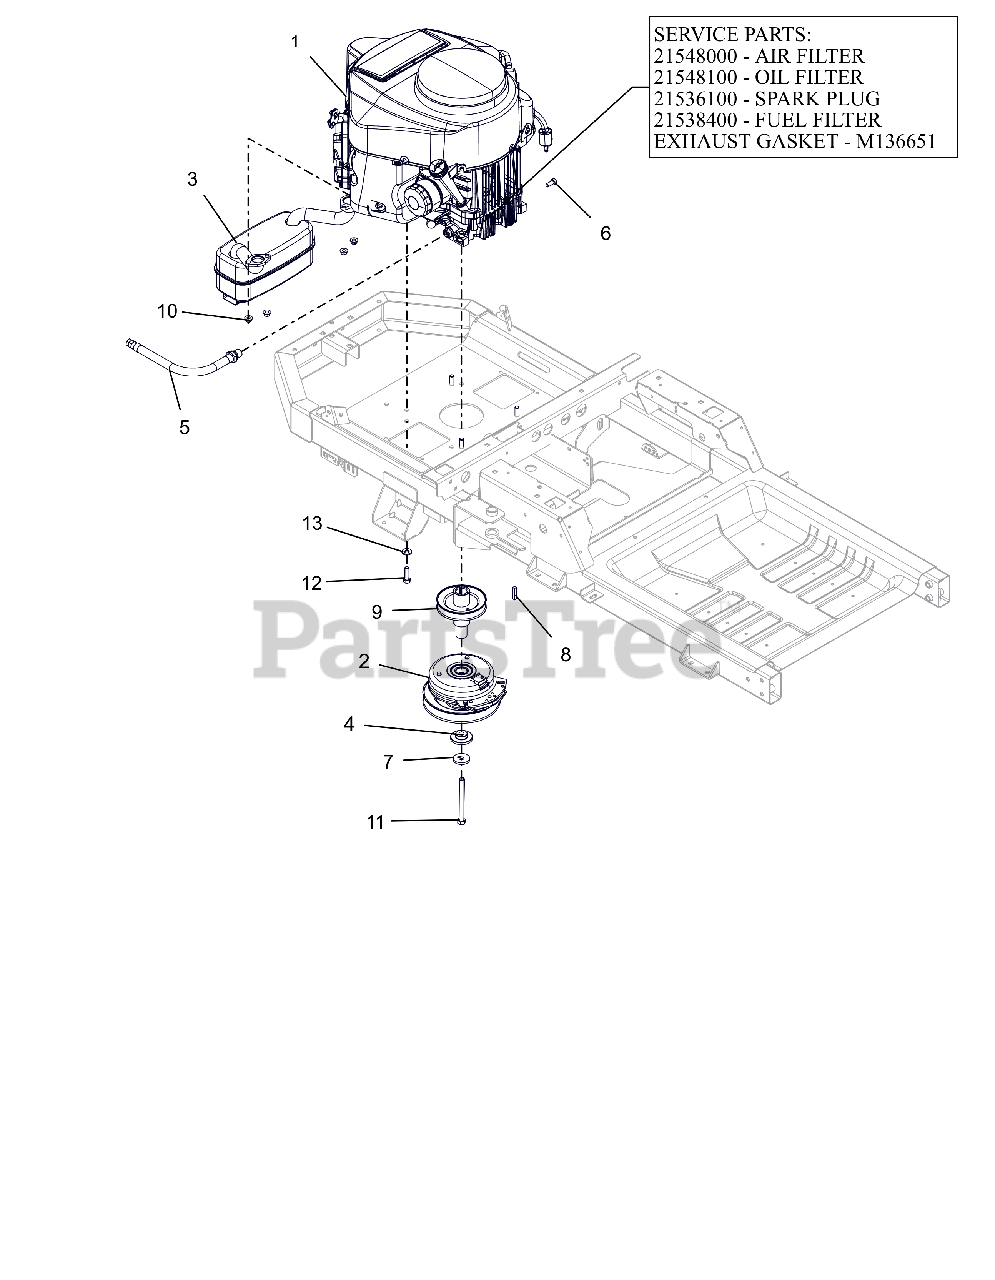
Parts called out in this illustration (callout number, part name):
1	ENGINE, KAWASAKI FR651V 22HP
1	AIR FILTER, KAWASAKI FR
1	OIL FILTER, KAWASAKI FR
1	PLUG, SPARK
1	FUEL FILTER - KAWASAKI
1	GASKET, MUFFLER #
2	CLUTCH,105FTLB MONOPOLE 6.83"
3	MUFFLER - KAWASAKI
4	BSHG-FLG .469X1.06X.574X2.0
5	HOSE, OIL DRAIN
6	BLT, HEX M8-1.25X20 G8.8 ZCC
7	WASHER, 7/16" SPRING DISK
8	KEY-SQ .25 X 1.25 X .25 SAE
9	WLDMT, DRIVE SHEAVE-X
10	NUT-LK-TOP-FLG M8 ZCC
11	BLT, HEX .44-20X4.50 G8 ZCC NT
12	BLT, HEX .38-16X1.25 G5 ZCC NT
13	WASHER, 3/8" SPRING DISC
